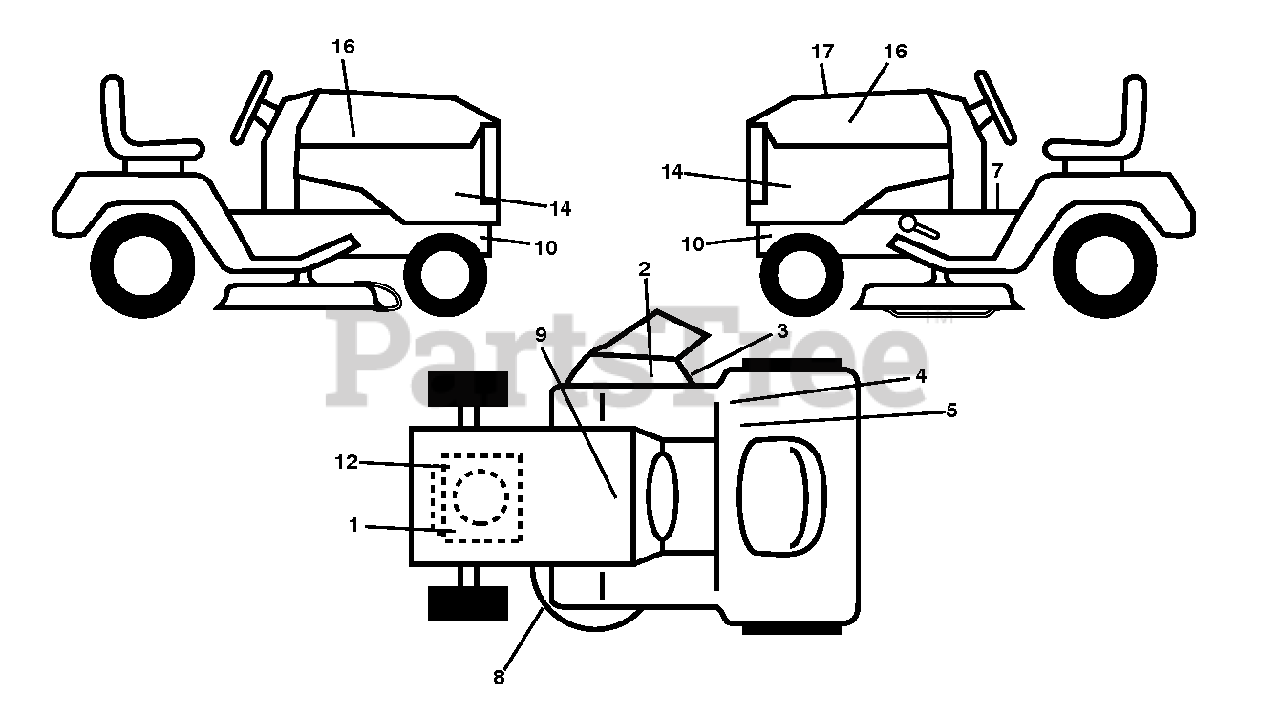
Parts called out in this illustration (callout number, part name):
1	DECAL.ENG.BS.656CC.ENDUR.38227
2	DECAL, DECK DEFLECTOR, WARNING
3	DECAL.DFLCTR.WARNNG.CTFNGR.SYM
4	DECAL.80.DBA.AUSTRALIA
5	DECAL.TICKMARK.6MIL.AUSTRALIA
7	DECAL.READ.OWN.MAN.SYMBOL.LT
8	DECAL.V-BELT.SCH.42/46"MEC/ELE
9	DECAL BTRY SYMBOLS
10	DECAL.CHASSIS.HOT.MUFFLER
12	DECAL.ENGINE.WARNING
14	DECAL.SDPNL.HUSQGT.TS242.RH/LH
16	DECAL.BADGE.170MM.TEXTLOGO.
17	DECAL.RPL.BSM40.END.TLW.42RK46
